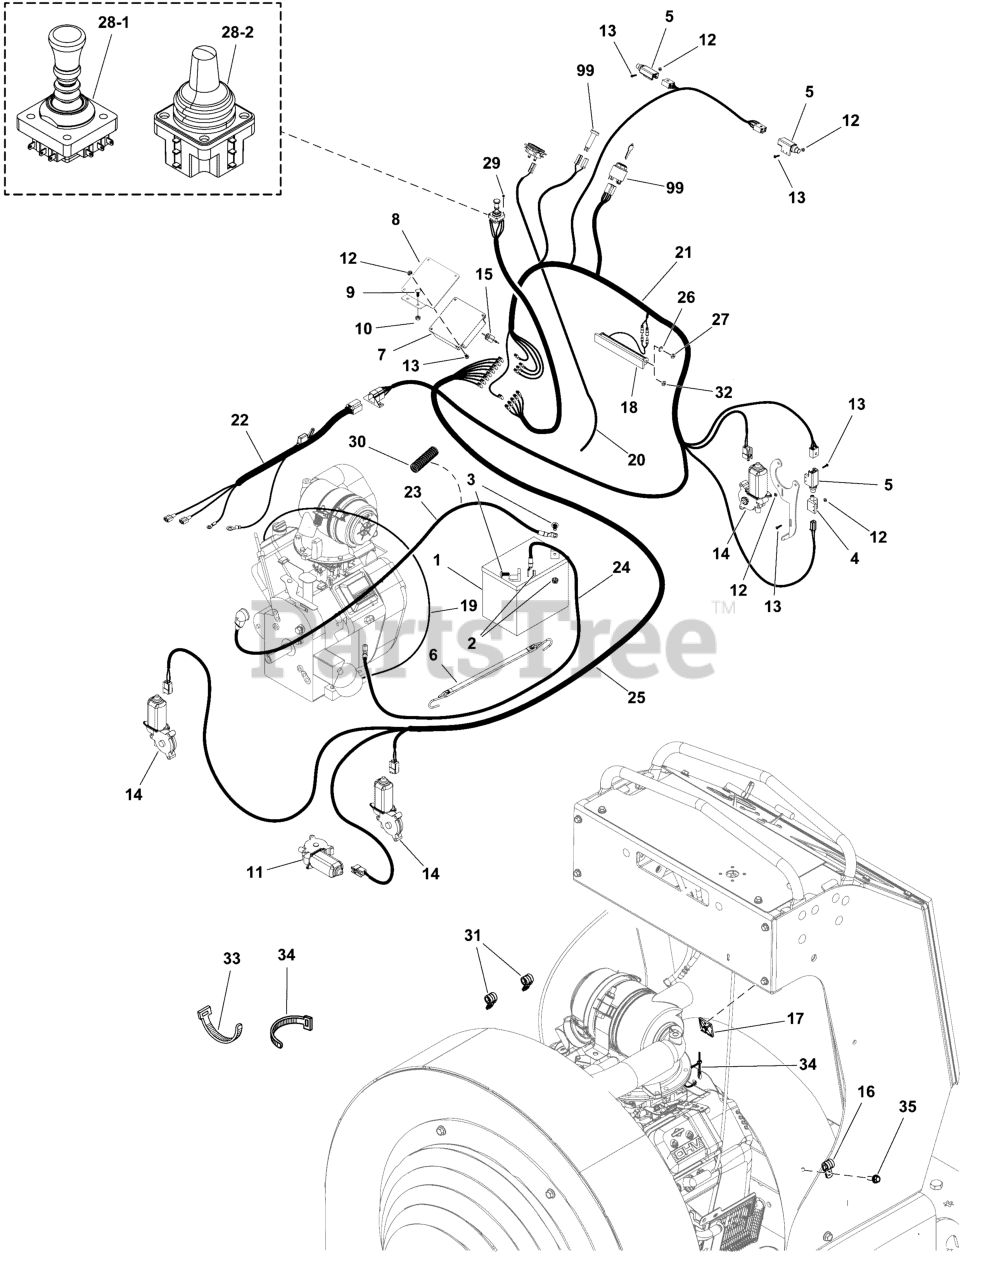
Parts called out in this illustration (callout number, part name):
1	BATTERY
2	NUT, 5/16-18 HEX SERRATED FLANGE (SMALL)
3	SCREW, 5/16-18x0.750, GR5, WHIZ-LOCK, ZC
4	SWITCH, PLUNGER, N.C.
5	SWITCH, SAFETY(2P)
6	STRAP, BATTERY
7	KIT, RELAY, CONTROL MODULE
8	BRACKET, RELAY MOUNT - BLK
9	BOLT,1/4-20X0.750,GR5,STD NECK,SQ,ZC/CL
10	NUT, 1/4-20 HEX SERR. FLANGE
11	MOTOR, DEFELCTOR, LEFT
12	NUT, #10-32, HEX, KEPS, ZC/CL
13	SCREW, #10-32 X 3/4, ALLEN, SS
14	DEFLECTOR, Motor
15	CIRCUIT BREAKER, 15A A-RESET
16	CLAMP, VINYL INSULATED, .50
17	MOUNT, ZIPTIE, X3
18	HEADLIGHT ASSY - LED
19	WIRE HARNESS, OIL PRESSURE SWITCH,X3
20	WIRE HARNESS, TACH X3,Z3
21	WIRE HARNESS, MAIN, X3 JOYSTICK
22	WIRE HARNESS,VANGUARD 23HP
23	BATTERY CABLE, POS, 24.69, 5/16-5/16
24	BATTERY CABLE, NEG, 13.50, 5/16-3/8
25	WIRE HARNESS, DEFLECTOR, X3 JOYSTICK
26	WASHER, 5MM, STAR, CZ
27	NUT, HEX, M5X.8MM, NYLON INSERT
28-1	KIT, JOYSTICK UPDATE
28-2	JOYSTICK ASSEMBLY, DEBRIS BLOWER
29	SCREW, #8-32 X 3/8, ALLEN, SS
30	WIRE LOOM, 3/8 ID X 17.5 IN
31	CLAMP, VINYL INSULATED, .75
32	NUT, HEX, M6-1, NYLON INSERT
33	TIE, SELF-LOCKING, 12"
34	TIE, SELF-LOCKING, 6"
35	BOLT, 1/4-20 X 3/4, FLANGE, CZ
99	Refer to: Instrument Control Panel Group
